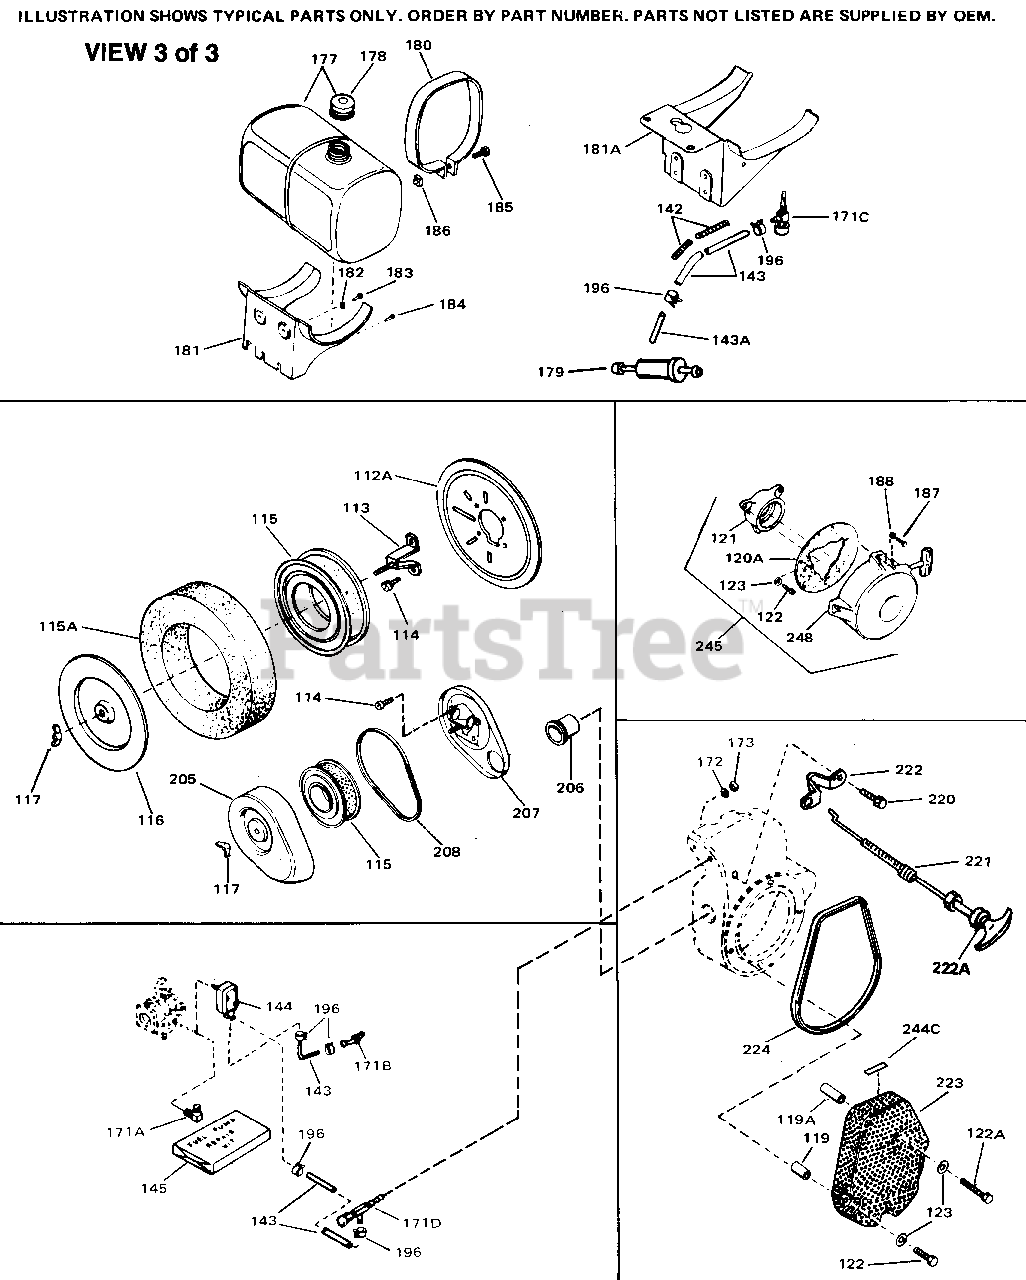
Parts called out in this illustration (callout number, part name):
114	Screw, 10-32 x 5/8"
115	Air Filter
117	Nut, Wing
119	Spacer, Screen
122	Screw, 1/4-20 x 3/4"
123	Lockwasher
143	Fuel Line (8.62") equired)
143	Fuel Line (Braided 16")(41 cm) As req uired
143	Fuel Line (Braided 32")(81 cm) As req uired
148	Alt.Coil Ass'y. (Incl. 162,163,163A) 20 amp
178	Fuel Cap (Red Plastic) (Spurt resista nt, High profile) (Use as required)
178	Fuel Cap (White Plastic)(Std) As requ ired
196	Fuel Line Clamp
218	Screw, T-30, 1/4-20 x 1/2"
245	Rewind Starter Kit (Incl. 120A, 121, 122, 187, 188 & 248) (Use as required )
